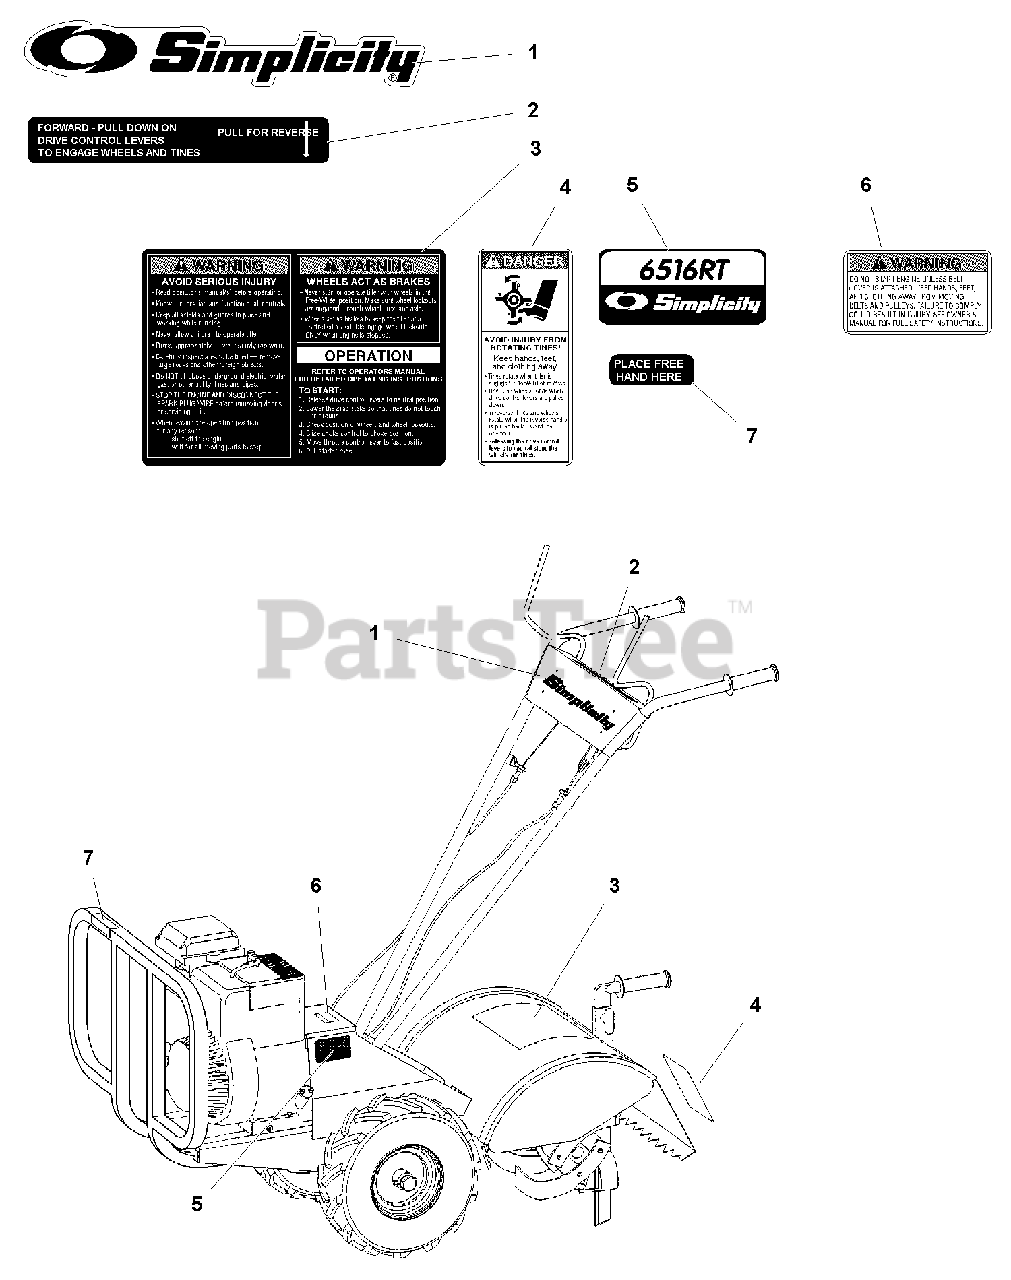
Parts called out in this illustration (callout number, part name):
1	DECAL, SIMPLICITY, w/Logo, Fuel Resistant 10"
2	DECAL, Console Forward/Reverse Instructions
3	DECAL, Hood, Operator Instructions Label
4	DECAL, Danger, Tine Hood Label
5	DECAL, Belt Cover
6	DECAL, Warning, Belt Cover
7	DECAL, Brush Bar
